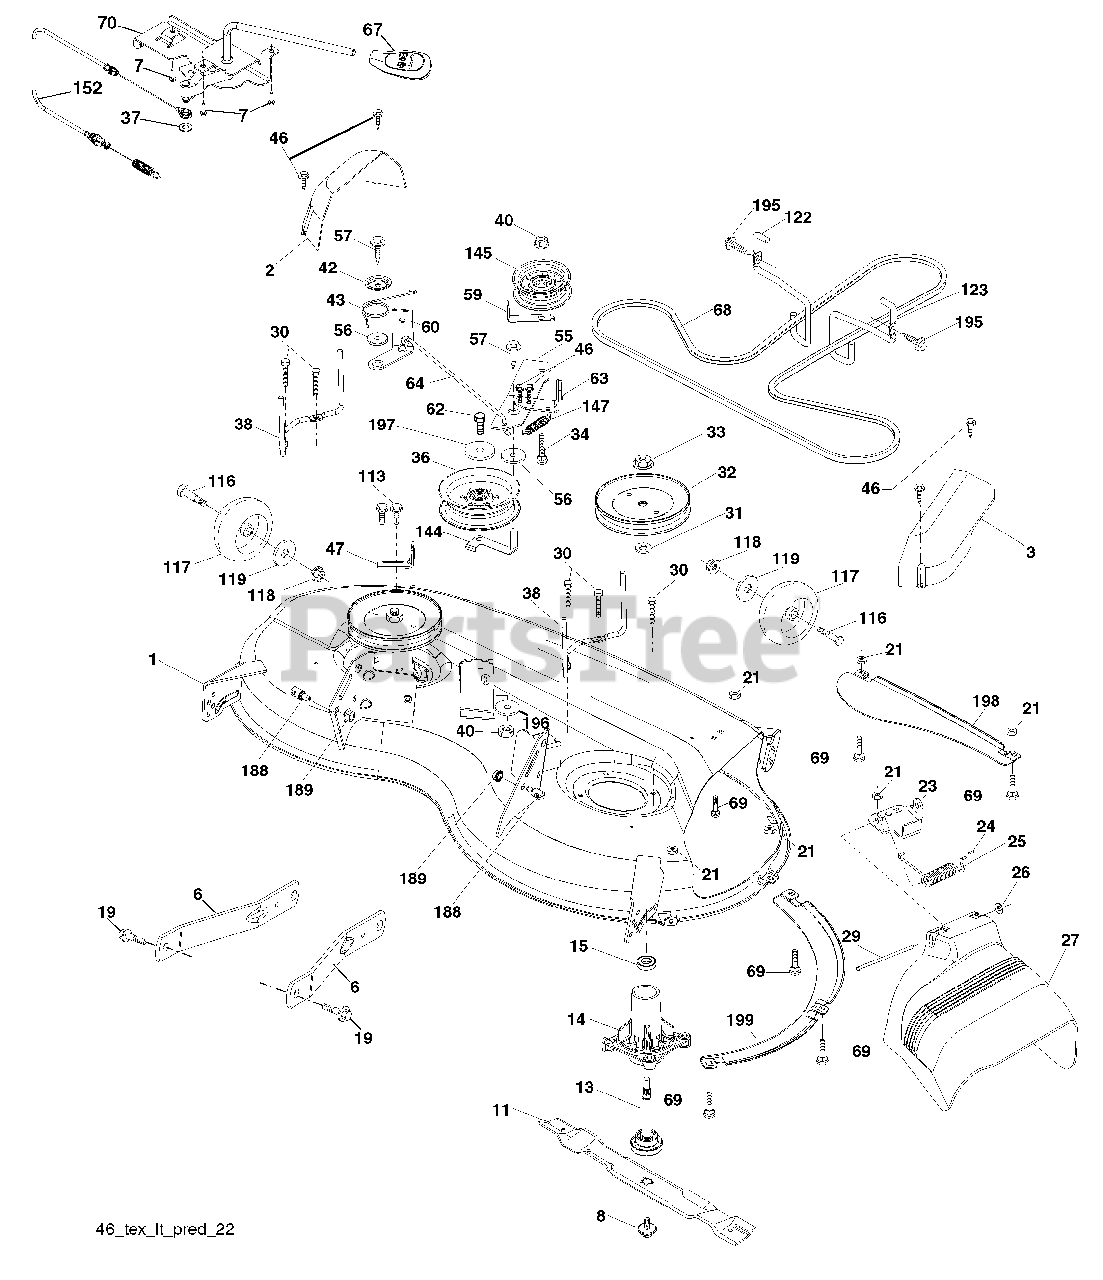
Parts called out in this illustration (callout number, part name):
2	Cover Mandrel
3	Cover Mandrel
6	Arm Suspension
7	Screw 10 x 3/4 Single Hex
8	Bolt/Washer asm 7/16-20 unf
11	Blade Mower
13	Shaft Assembly, Mandrel
14	Housing, Mandrel
15	Bearing, Ball, Mandrel
19	Bolt, Shoulder
21	Nut
23	Bracket, Deflector
24	Cap, Sleeve
25	Spring, Torsion, Deflector
26	Nut, Push
27	Shield, Deflector
29	Rod, Hinge
30	Screw Thdrol Rolling Wsh Hd
31	Washer, Spacer
32	Pulley, Mandrel
33	Nut, Toplock, Flanged
34	Bolt Carr Sh. 3/8-16 x 1-1/2 Gr. 5
36	Pulley, Idler, Flat
37	Washer 13/32 x 13/16 x 16 Ga.
38	Keeper Belt LH Mandrel
40	Nut, Lock Flg. 3/8-16 unc
42	Spring Trosion Brake
43	Spring Torsion Retainer
46	Screw
47	Bracket Clutch Cable
55	Arm, Idler
56	Spacer, Retainer
57	Screw Hexwsh Thd 3/8-16 x 1
59	Guard, Tuv Idler (94)
60	Arm Brake Mower
62	Bolt Fin Hex 3/8-16 x 2-1/4 Gr. 5
63	Arm Brake Mower
64	Linkage Brake
67	Handle, Clutch Cable
68	V-Belt
69	Bolt
70	Clutch Asm. Manual
113	Screw 5/16-18
116	Bolt, Shoulder
117	Wheel, Gauge
118	Nut, Crownlock 3/8-1
119	Washer 13/32 x 7/8 x 14 Ga.
122	Keeper Belt Eng. LH
123	Keeper Belt Eng. RH
144	Keeper Belt
145	Pulley Idler
147	Spring Return
152	Cable Clutch Manual w/Spr.
188	Stud Fastener
189	Nut Lock Hex Flange
195	Screw Hexwsh Thdrol 3/8-16 x 3/4
196	Washer 13/32 x 2 x 10 Ga
197	Washer 13/32 x 13/16 x 12 Ga.
198	Baffle Center Front
199	Baffle Front RH
199	Mandrel Assembly
199	Replacement Mower, Complete
